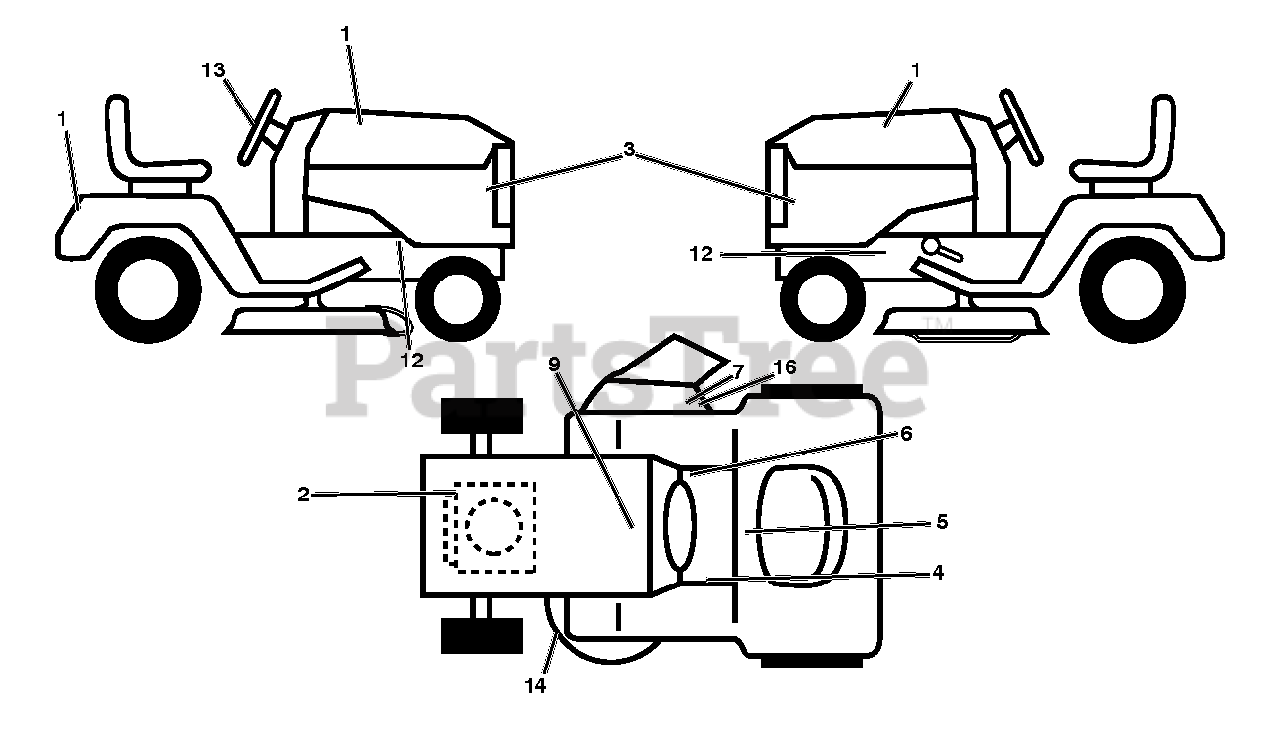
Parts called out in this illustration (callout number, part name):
1	DECAL, DIXON LOGO, DOMED
2	DECAL.ENGINE.WARNING
3	DECAL.SDPNL.22/42.KOHLER.DIX
4	DECAL.FNDR.SDLE.BRAKE.CLUTCH.6
5	DECAL.READ.OWN.MAN.SYMBOL.LT
6	DECAL.PARKING.BRAKE.SADDLE.LT
9	DECAL BTRY SYMBOLS
12	DECAL.CHASSIS.HOT.MUFFLER
13	DECAL.WHEEL.STEER.DIXON
14	DECAL.V-BELT.SCH.42/46"MEC/ELE
16	DECAL.CUTFINGER.CE.02
